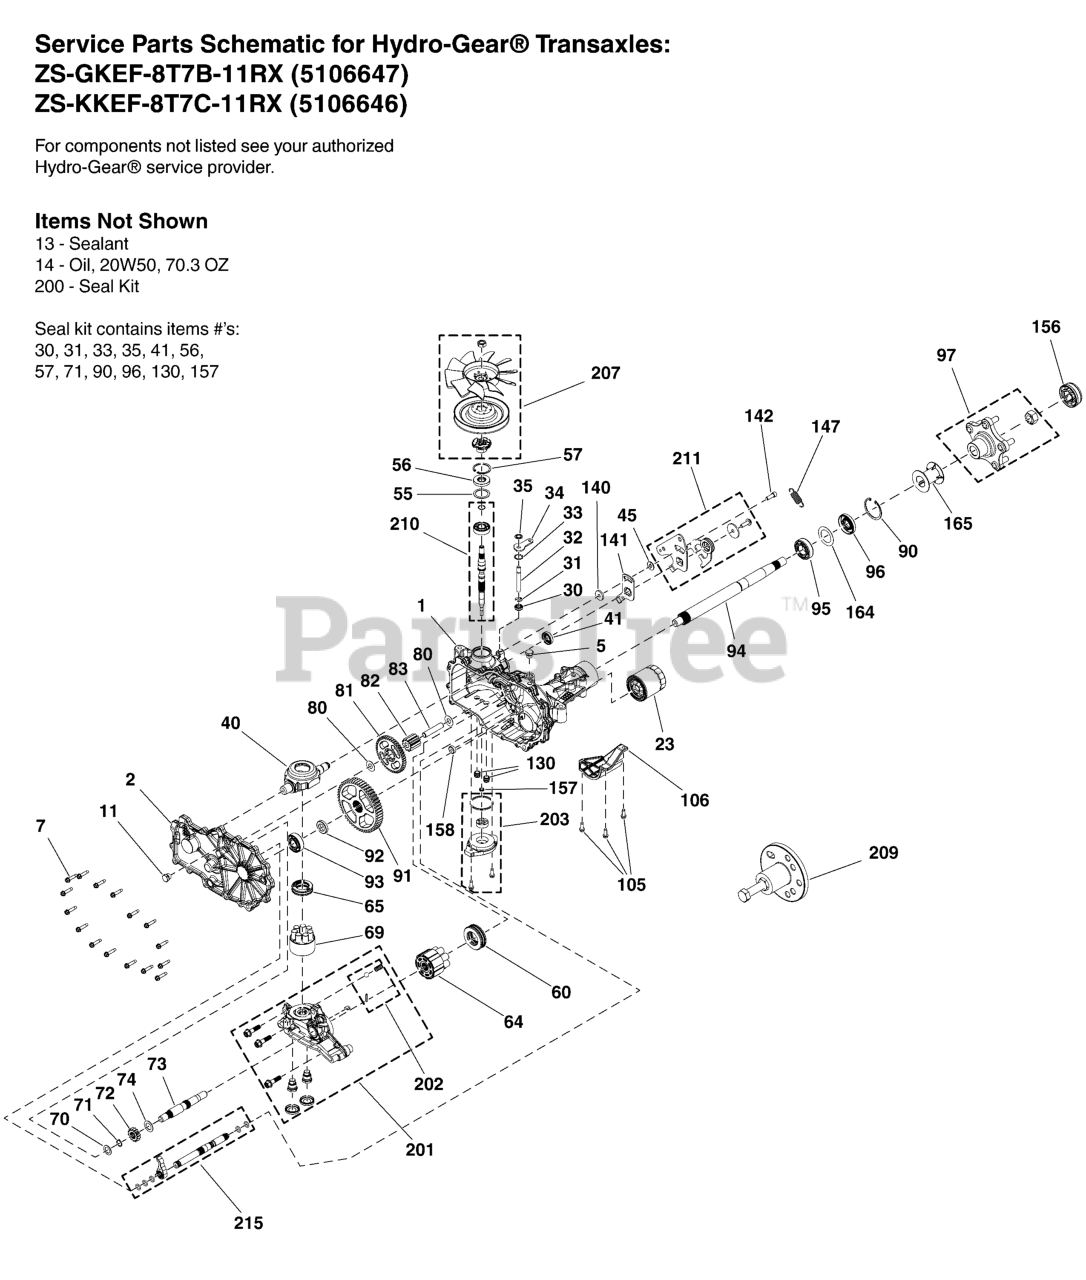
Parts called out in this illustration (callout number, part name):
1	KIT, MAIN HOUSING, RH, CHARGE, CONTROL
2	KIT, SIDE COVER RH
23	FILTER, OIL, ZT2800
30	SEAL, .375 X .750 X .25 LIP, H/G 51626
34	ARM, BYPASS
35	RING, RETAINING .375 EXTERNAL
40	SWASHPLATE, TRUNNION
41	SEAL, CONTROL ARM, 18X32X7, #51140
55	SPACER (50951)
56	SEAL, Lip, .67 x 1.58 x .276
57	RING, RET 2.06 INT,
64	KIT, 16cc CYLINDER BLOCK ASSEMBLY STEAM TREAT
65	BEARING, THRUST PLASTIC CAGE
70	WASHER, .63 X 1.00 X .05 FLAT
71	RING-SNAP (44145)
72	GEAR, 14T (STEEL)
73	SHAFT, MOTOR
74	WASHER, .71 X 1.16 X .04 FLAT
80	WASHER, .51 X 1.00 X .03 FLAT
82	GEAR, 11T (STEEL)
83	PIN, JACKSHAFT
90	RING, RETAINING 2.25 INTERNAL (50859)
93	KIT, BEARING (72749)
94	SHAFT, AXLE
95	BEARING BALL, 1.0 X 52 X 15 OPEN 6205M
96	KIT, SEAL, AXLE - HG# 53699
97	HUB, ZT3400, 71691
106	GUARD, FILTER, RH
130	TUBE, CHARGE TRIPLE O-RING
141	ARM, NEUTRAL RIGHT
142	SHCS, 5/16-24 X .875 (PATCH)
147	SPRING, Extension (Used on Hydro-Gear P/N ZC-AHBB-2A7B-1DPX and ZC-AHBB-2A7B-1DPX)
156	AXLE CAP,
157	KIT, GEROTOR SEAL
158	MAGNET
164	WASHER, 1.355 x 2.035 x .021 FLAT
165	DEBRIS GUARD HG #53496
200	KIT, SEAL - HG# 73239
201	KIT, CENTER SECTION, RH CHARGE
202	KIT, CHARGE RELIEF
203	KIT, CHARGE PUMP, ZT2800, ZT3100
207	KIT, FAN & PULLEY -
209	KIT, HUB PULLER
210	KIT, INPUT SHAFT (BEARING AND SHAFT ONLY)
211	KIT, RTN BIDIRECTIONAL
215	SEAL KIT BRAKE SHAFT ZT3400 LH 72753 NET
